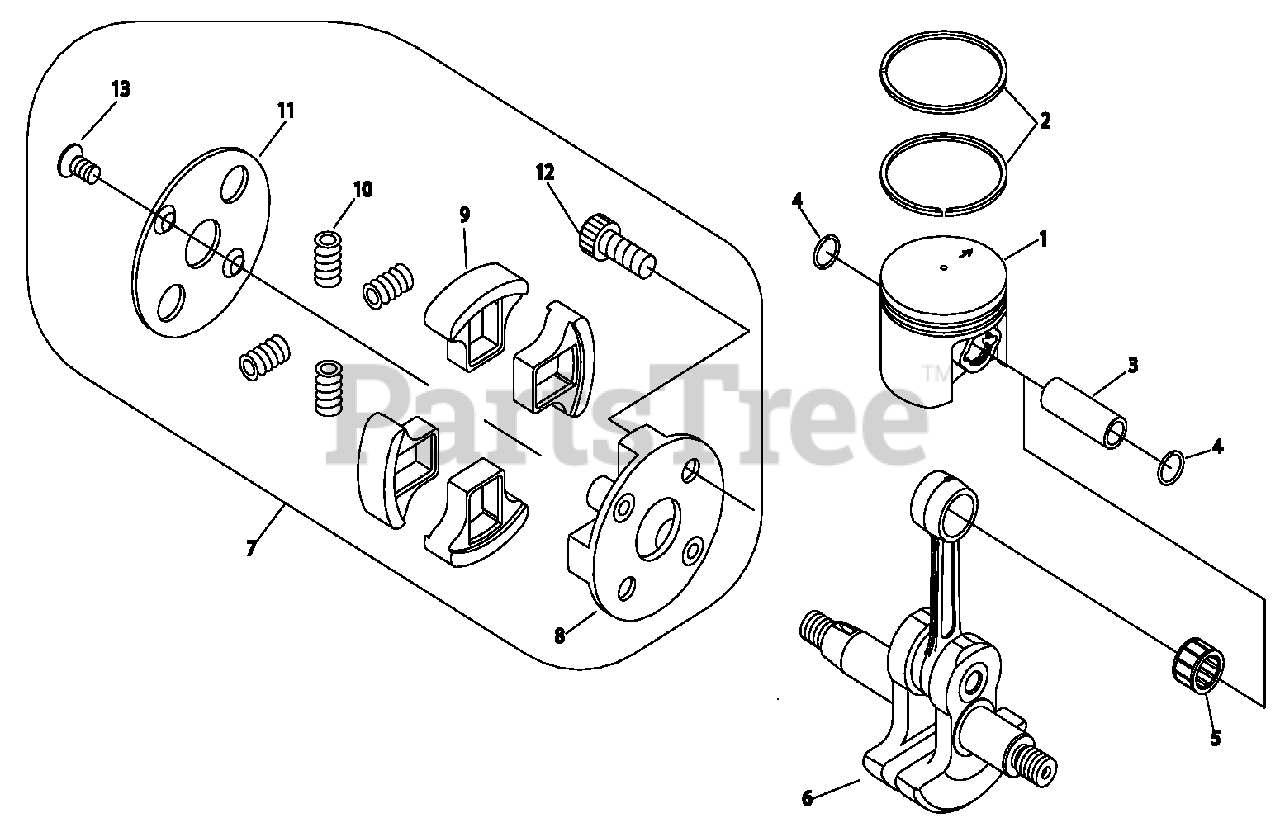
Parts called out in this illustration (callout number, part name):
1	PISTON
2	RING, PISTON
3	PIN, PISTON
4	RING, RETAINING
5	BEARING, NEEDLE
6	CRANKSHAFT ASSY
7	CLUTCH ASSY
8	HUB, CLUTCH
9	SHOE, CLUTCH
10	SPRING, CLUTCH
11	PLATE, CLUTCH
12	BOLT, CLUTCH
13	SCREW
